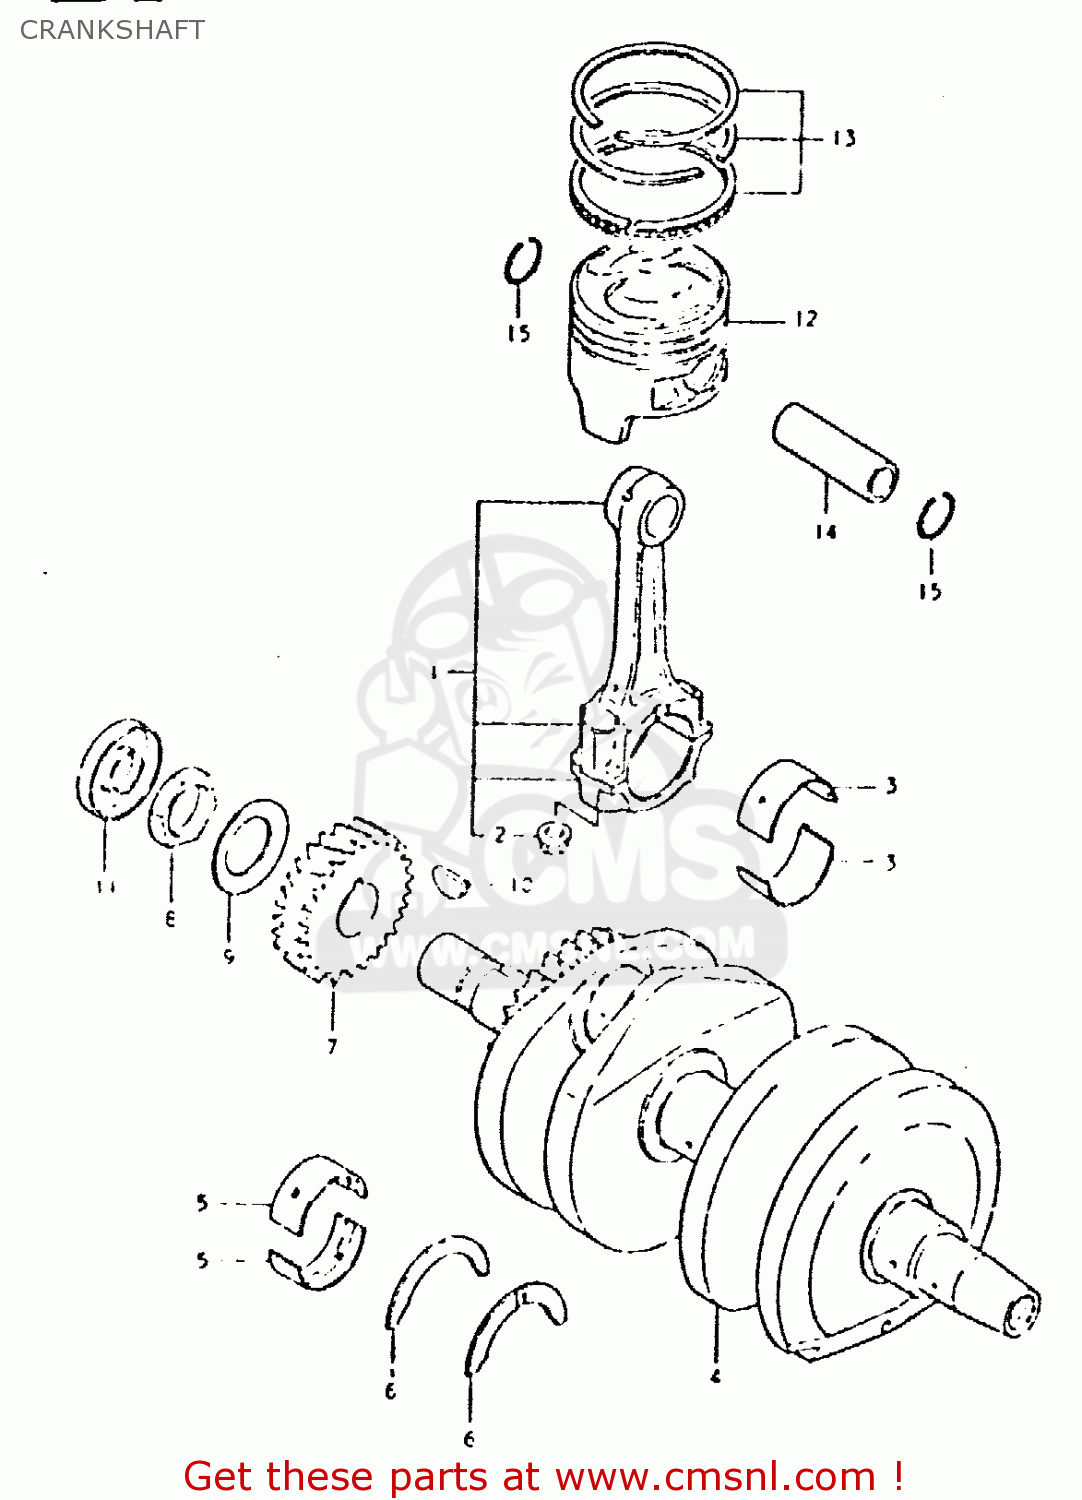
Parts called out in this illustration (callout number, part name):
1	ROD ASSEMBLY,CONNECTING
2	NUT
3	BEARING,CRANK PIN
4	CRANKSHAFT
5	METAL CRANKSHAFT
6	PLATE,CRANK THRUST
7	GEAR,PRIMARY DRIVE NO.28
8	NUT
9	WASHER
10	KEY
11	OIL SEAL
12	PISTON (STD)
13	RING SET,PISTON
14	PIN,PISTON
15	CIRCLIP,PISTON PIN
